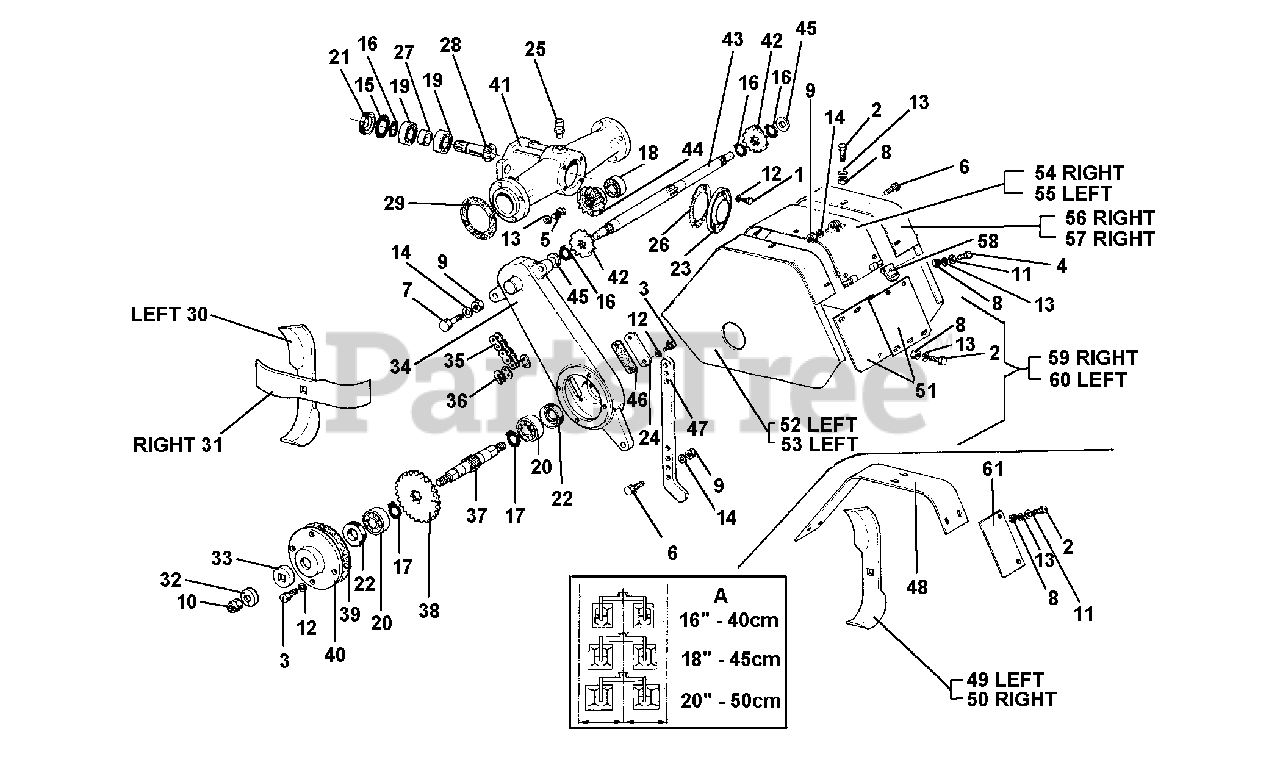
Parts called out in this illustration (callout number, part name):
1	SCREW TE M6 X 10 UNI 5739-5S
2	SCREW M8 X 16
3	SCREW TE M6 X 16
4	SCREW M8 X 20
5	SCREW M8 X 25
6	SCREW M10 X 30
7	SCREW M10 X 45
8	NUT, HIGH M8 UNI 5587-5S
10	NUT M16 X 1.5
11	WASHER, FLAT 8.4
12	WASHER, LOCK 6.4
13	WASHER, LOCK 8.4
14	WASHER, LOCK 10.5
15	CIRCLIP, INTERN. D 47
16	CIRCLIP EXTERN. D 20
17	CIRCLIP, D 32
18	BEARING 20 X 42 X 12 6004
19	BEARING 20 X 47 X 14 6204
20	BEARING 25 X 52 X 15 6205
21	OIL SEAL 20 X 47 X 7
24	PLATE CHAIN CONTROL
28	CONICAL PINION
34	CENTRAL CRANKCASE
38	CHAIN BEVEL GEAR
41	CENTRAL CRANKCASE
42	BEVEL GEAR PINION
44	GEAR RING BEVEL
47	ROTARY HOE CENTRAL KNIFE
49	L.H. DOUBLE HOE
50	R.H. DOUBLE HOE
52	L.H. SIDE ELEMENT
53	L.H. OUTSIDE ELEMENT
54	R.H. CENTRAL ELEMENT
55	L.H. CENTRAL ELEMENT
56	R.H. CENTRAL ELEMENT
57	R.H. OUTSIDE ELEMENT
61	FLAP WIDENING
